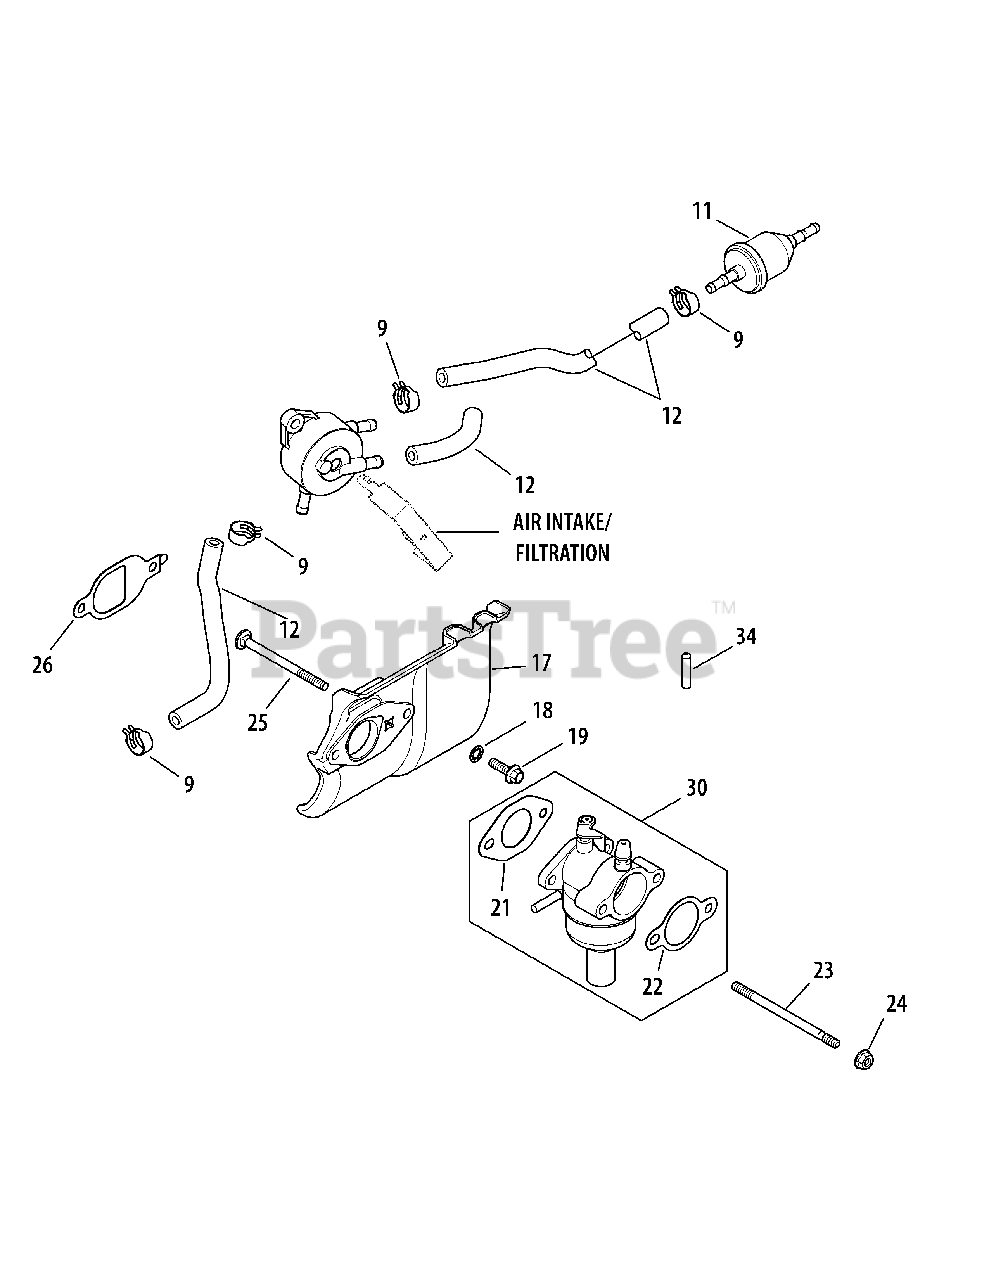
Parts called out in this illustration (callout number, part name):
9	Hose Clamp, 1/2
12	Fuel Line
17	Heat Deflector Kit
18	Int. Tooth Lock Washer, 1/4
19	Flange Screw, M6 X 1.0 X 20
21	Gasket, Carburetor
22	Gasket, A/C Base
23	Stud, M6 X 1.0 X 100
24	Flange Nut, M6 X 1.0
25	Carburetor Stud
26	Heat Deflector Gasket
30	Carburetor Kit (Inc. 21 & 22)
